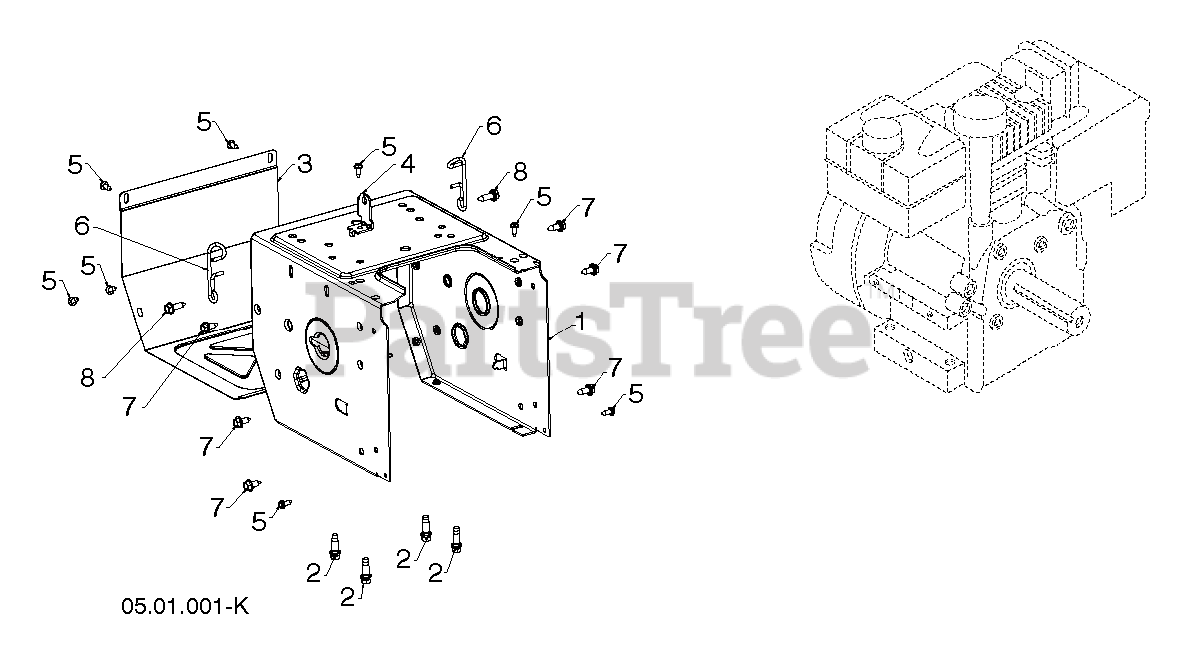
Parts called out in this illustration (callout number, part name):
1	FRAME MS 668
2	BOLT 3/8-16X1-1/8
3	COVER COVER.FRAME MS668 ORANGE
4	BRACKET.SHIFTER.BZP
5	SCREW.HEX HEAD W/COLLAR 1/4-20
6	WIREFORM.SUPPORT.CABLE
7	BOLT.HEX.HD.WASHER.5/16-18X.75
8	SCREW HEX_SERR_HD_5_16-18X1.0
